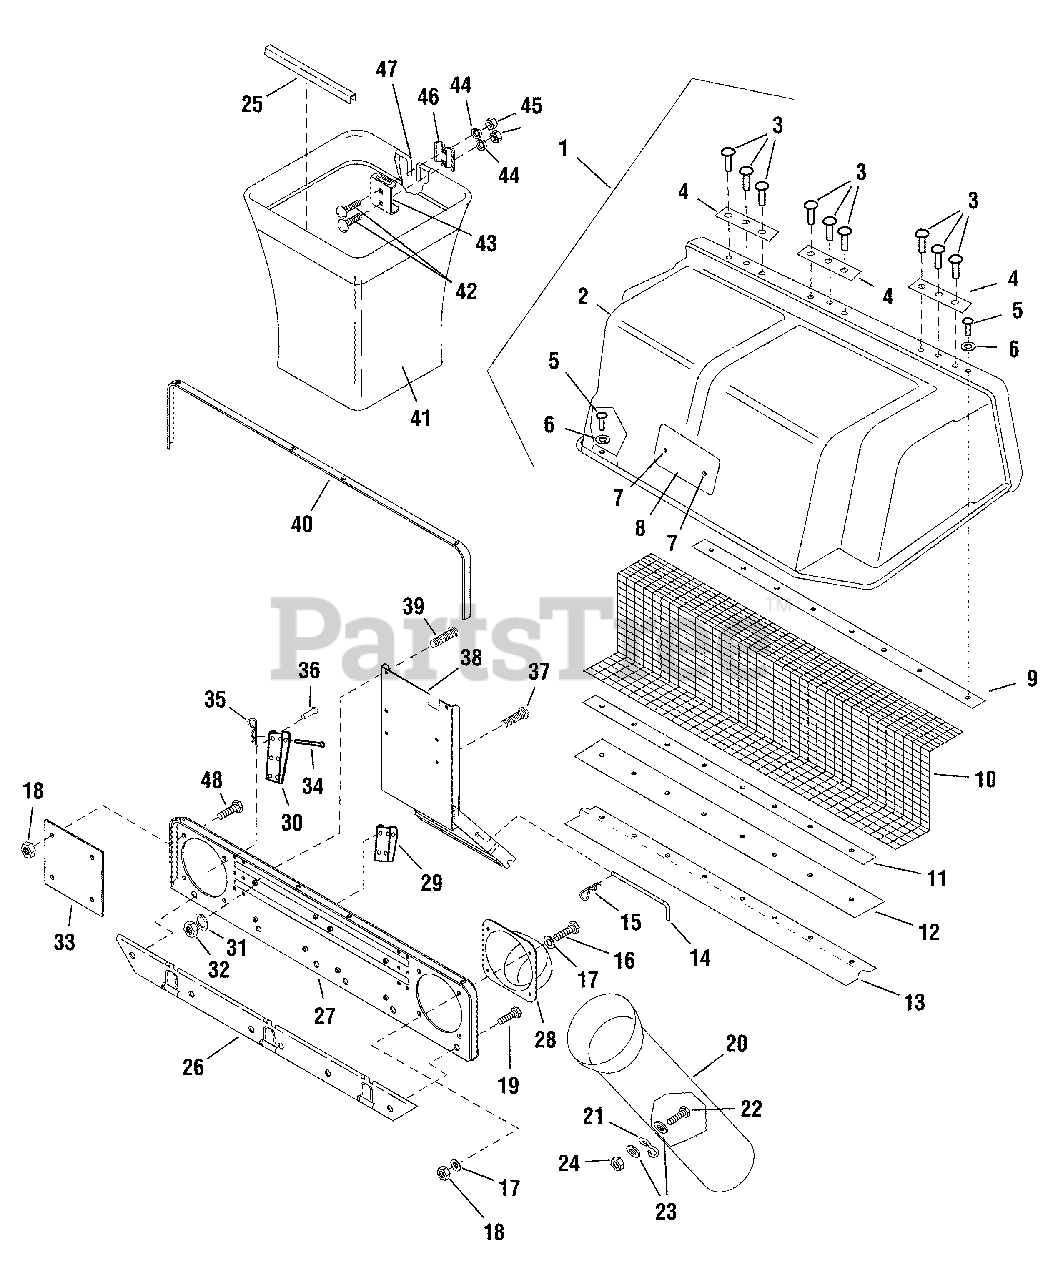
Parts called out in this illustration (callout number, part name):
1	COVER & SCREEN ASSEMBLY (Inc. Ref. No. 2,3,4,5,6,9,10,11,12,13)
2	COVER, GRASS CATCHER
4	PLATE ASSSEMBLY
7	CLIP, Canoe
8	DECAL, Saftey
11	CLAMP, Seal
13	ANGLE, Screen
16	CAPSCREW, Hex Head, 5/16-18 x 1
17	WASHER, 5/16
18	LOCKNUT, 5/16-18
19	CAPSCREW, Taptite, 1/4-20 x 1/2
22	CAPSCREW, Hex Head 1/4-20 x 7/8
23	WASHER, 1/4
24	LOCKNUT, 1/4-20
26	BRACKET ASSEMBLY
27	PLATE ASSEMBLY
31	LOCKWASHER, 5/16
32	NUT, 5/16-18
34	PIN, 3/8 x 2-3/4
35	PIN, Hair
36	RIVET
37	CARRIAGE BOLT, 5/16-18 x 1-1/4
38	SUPPORT ASSSEMBLY
39	CARRIAGE BOLT, 5/16-18 x 3/4
42	CARRIAGE BOLT, 5/16-18 x 3/4
44	LOCKWASHER, 5/16
45	NUT, 5/16-18
47	HOOP, Basket Frame
48	CAPSCREW, 5/16-18 x 3/4
